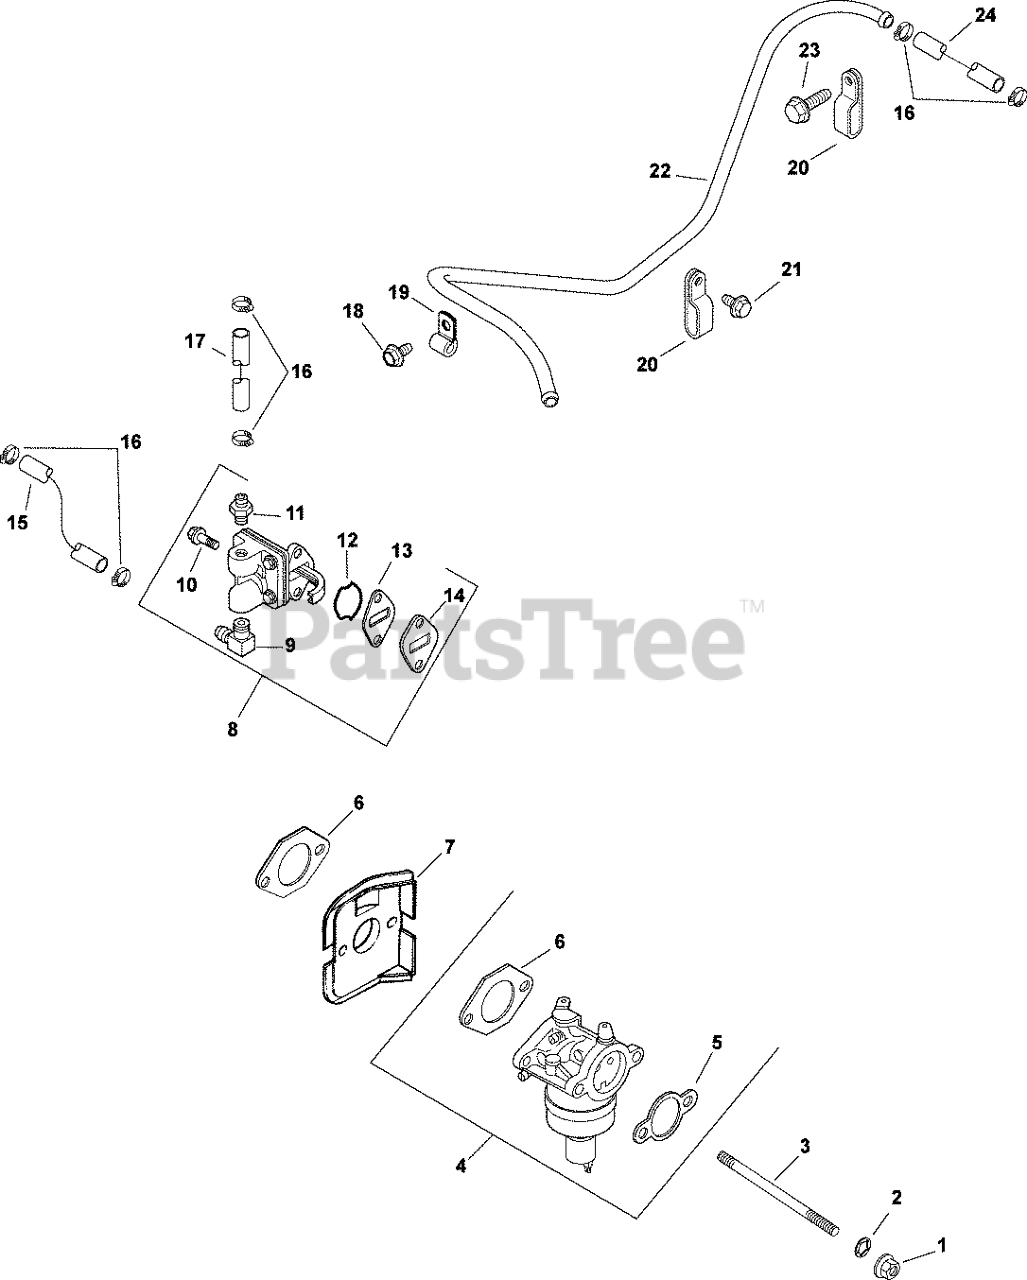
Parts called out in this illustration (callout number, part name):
1	NUT, FLG M6X1.0
2	WASHER, INT TOOTH LOCK 1/4"
3	STUD,M6X1.0X116
4	KIT, CARBURETOR
5	GASKET, AIR CLEANER BASE
6	GASKET, CARBURETOR
7	DEFLECTOR, HEAT
8	KIT, FUEL PUMP
9	CONNECTOR, 90 DEG. HOSE
10	SCREW, LBD SKT M6x1.0x20-(#25086403S)
11	KIT, STRAIGHT FITTING
12	O-RING, FUEL PUMP
13	GASKET, FUEL PUMP
14	SPACER, FUEL PUMP
15	FUEL LINE - USE 25 111 81-S
16	CLAMP, HOSE (KM)-USE 25 237 31-S
17	LINE, FUEL
18	SCREW, THRD FRM M5X0.8X10
19	CLIP, TUBE & WIRING (KM)
21	SCREW, FLG THD FRM M5X.8X10
22	LINE, FUEL
23	SCREW,FLG THD FRM M6X1.0X20-(#25086396S)
24	LINE - DISCONTINUED
